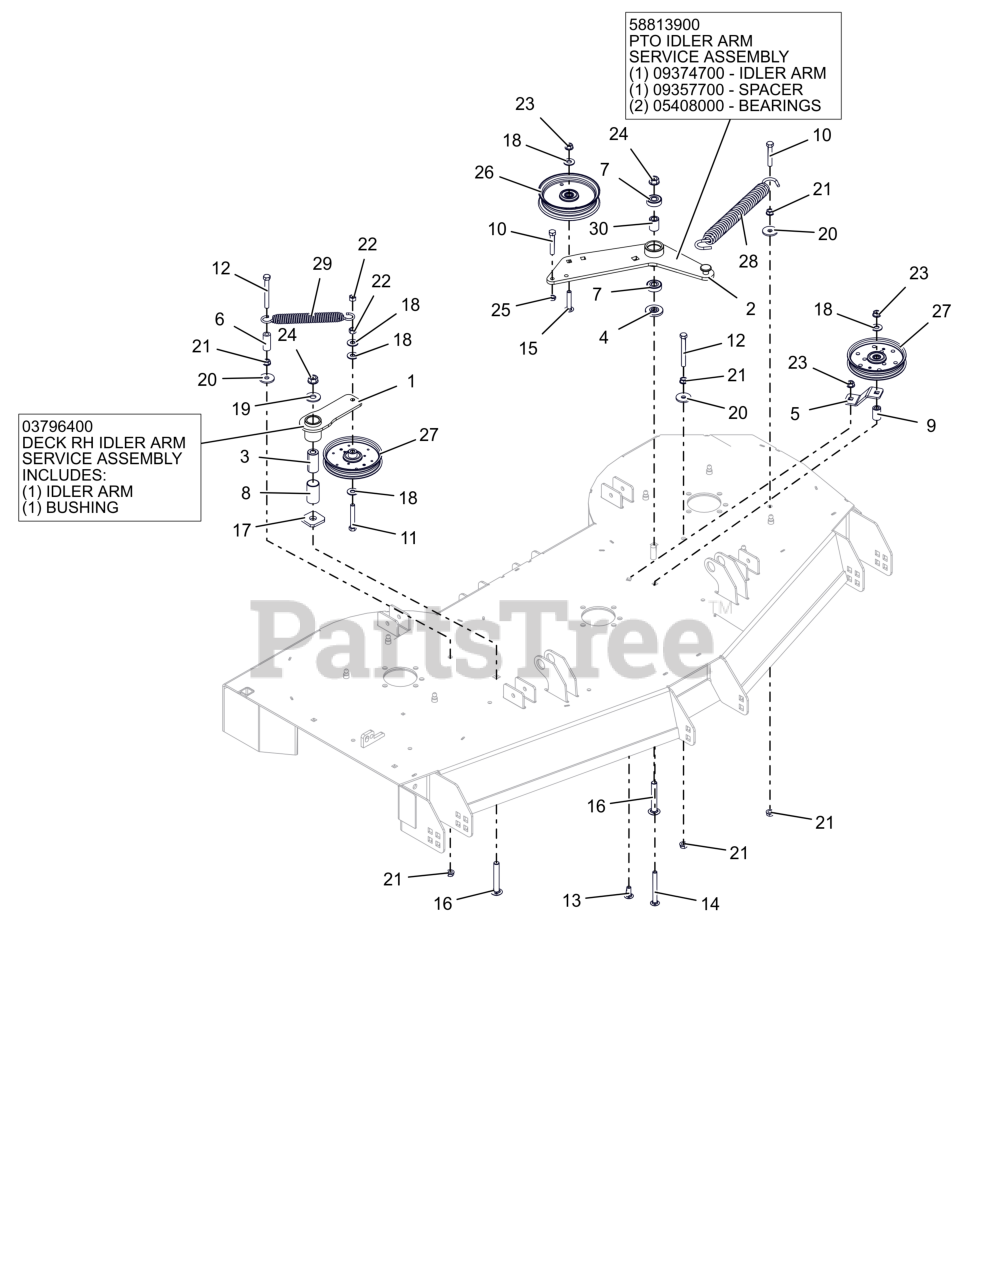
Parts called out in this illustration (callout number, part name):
1	WMT, IDLER ARM - BLACK
1	ASM, IDLER ARM (DECK)
2	WLDMT, IDLER ARM PT660
2	PTO IDLER ARM
2	SPACER .510 X .867 X 1.1485
2	BRG-BALL .500X1.38X.437
3	BSHG, SPCR .502X.997X2.03 PM
4	SPACER, IDLER ARM
5	PTO FIXED IDLER MTG BRKT -RED
6	HOSE, .38 X 1.65
7	BRG-BALL .500X1.38X.437
8	BSHG, 1.00X1.125X1.937
9	BUSHING, SLV .380X.750X1.190
10	BLT,HEX .38-16X2.25 G5 ZCC
11	BLT, HEX .38-16X2.50 G5 ZCC
12	BLT, HEX .38-16X3.25 G5 ZCC
13	BLT,RHSSN .38-16X1.00 G5 ZCC
14	BLT,RHSSN .38-16X3.50 G5 ZCC
15	BLT,RHSSN.375-16X2.00 G5 ZCC
16	BTL,RHSSN .500-13 X 3.25 G5 ZCC
17	WSHR-FLT .640X1.75X.250
18	WSHR,FLT .438X1.00X.083 ZCC
19	WSHR,FLT .563X1.375X.109 ZCC
20	WSHR,FLT .406X1.375X.135 ZCC
21	NUT, SPNLK-FLG .38-16 G5 ZCC
22	NUT-LK-CTR .38-16 ZC120
23	NUT-LK-CTR-FLG .375-16 GF ZCC
24	NUT-LK-CTR-FLG .500-13 GG ZCC
25	NUT-JAM .375-16 G2 ZCC
26	IDLER- FLAT - 5.00" X .75"
27	IDLER- 5" FLANGED
28	SPRING, EXTENSION
29	SPRING- EXTENSION
30	SPACER .510 X .867 X 1.1485
